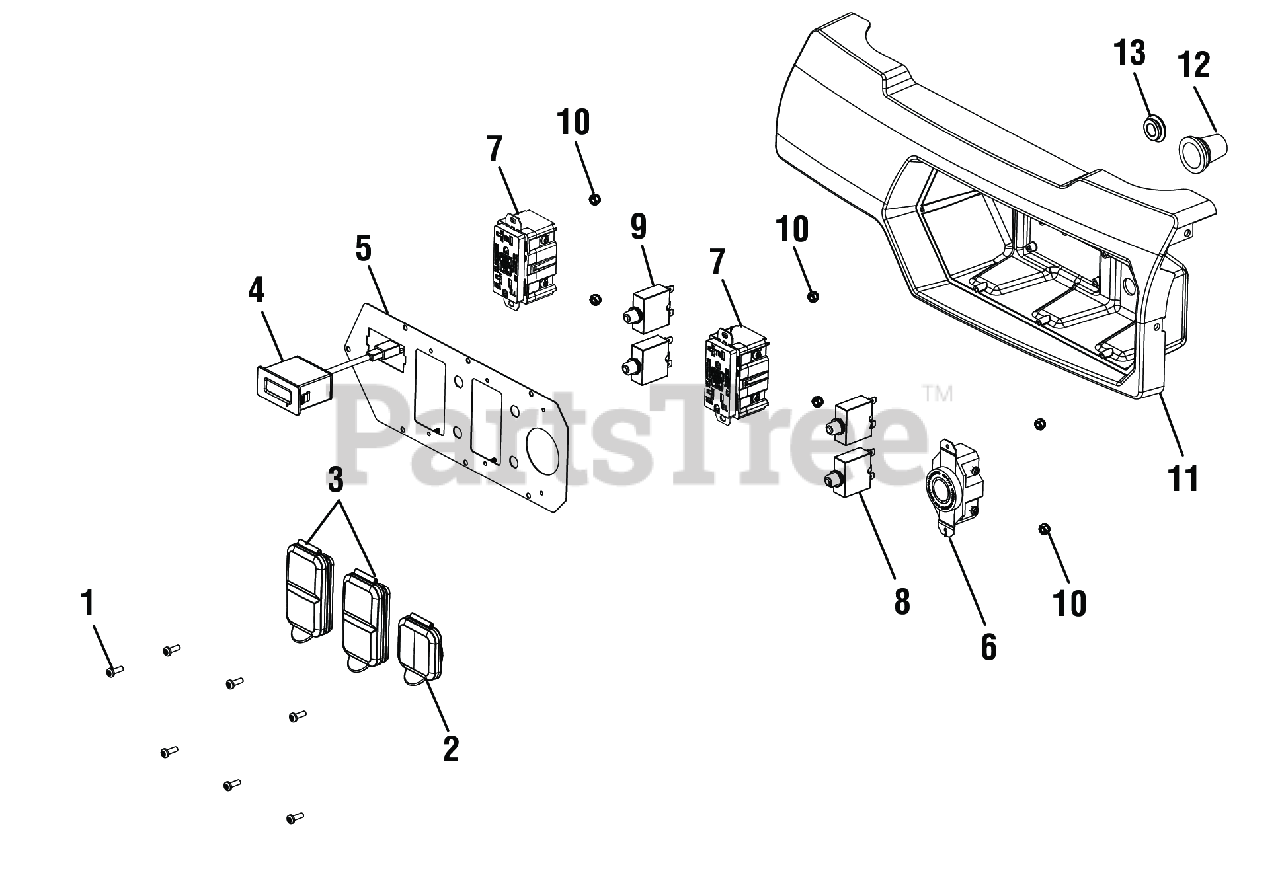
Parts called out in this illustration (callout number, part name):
1	Screw (#8-18 x 1/2 in., T20 Torx Pan Hd.)
2	240 Volt ReceptacleRain Cover
3	120 Volt Receptacle Rain Cover
4	Digital Display
5	Front Panel
6	Twist Lock Recepticle (120/240 Volt, 30 Amp, L14-30)
7	120 Volt Duplex GFCI Receptacle
8	Circuit Breaker (27 Amp)
9	Circuit Breaker (20 Amp, 125 Volt)
10	Lock Nut (M4)
11	Control Box (Back Panel)
12	Wiring Rubber Boot
